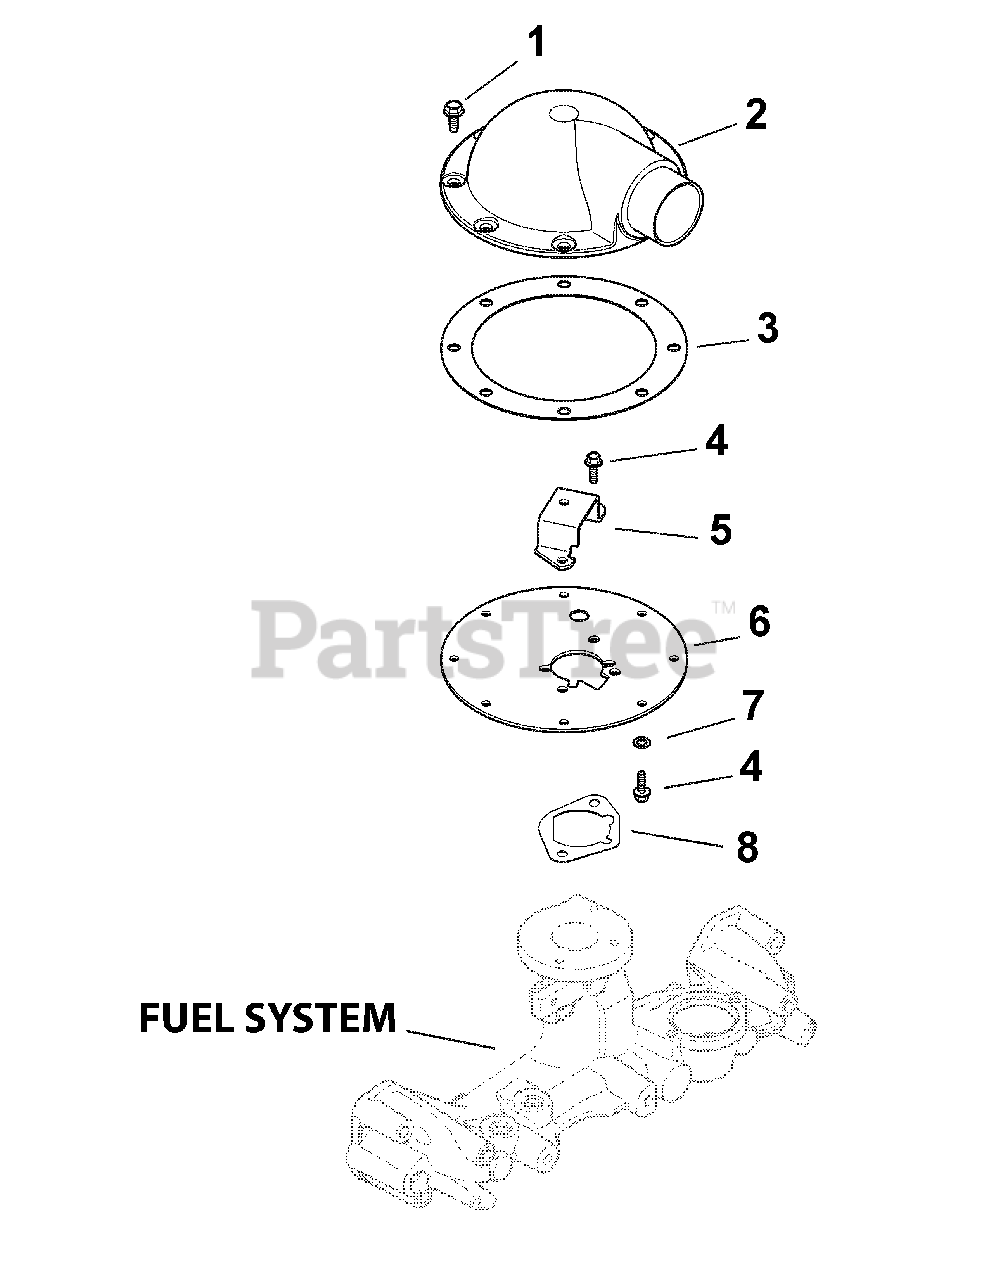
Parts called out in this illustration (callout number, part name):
1	Screw, Flg Thd Frm, M6x1.0x16
2	Adapter, Air Intake
3	Gasket, Air Cleaner Adapter
4	Screw, Hvy Flg, M5 x .8 x 16
5	Bracket, Air Cleaner
6	Adapter, Plate
8	Gasket, Air Cleaner Base
